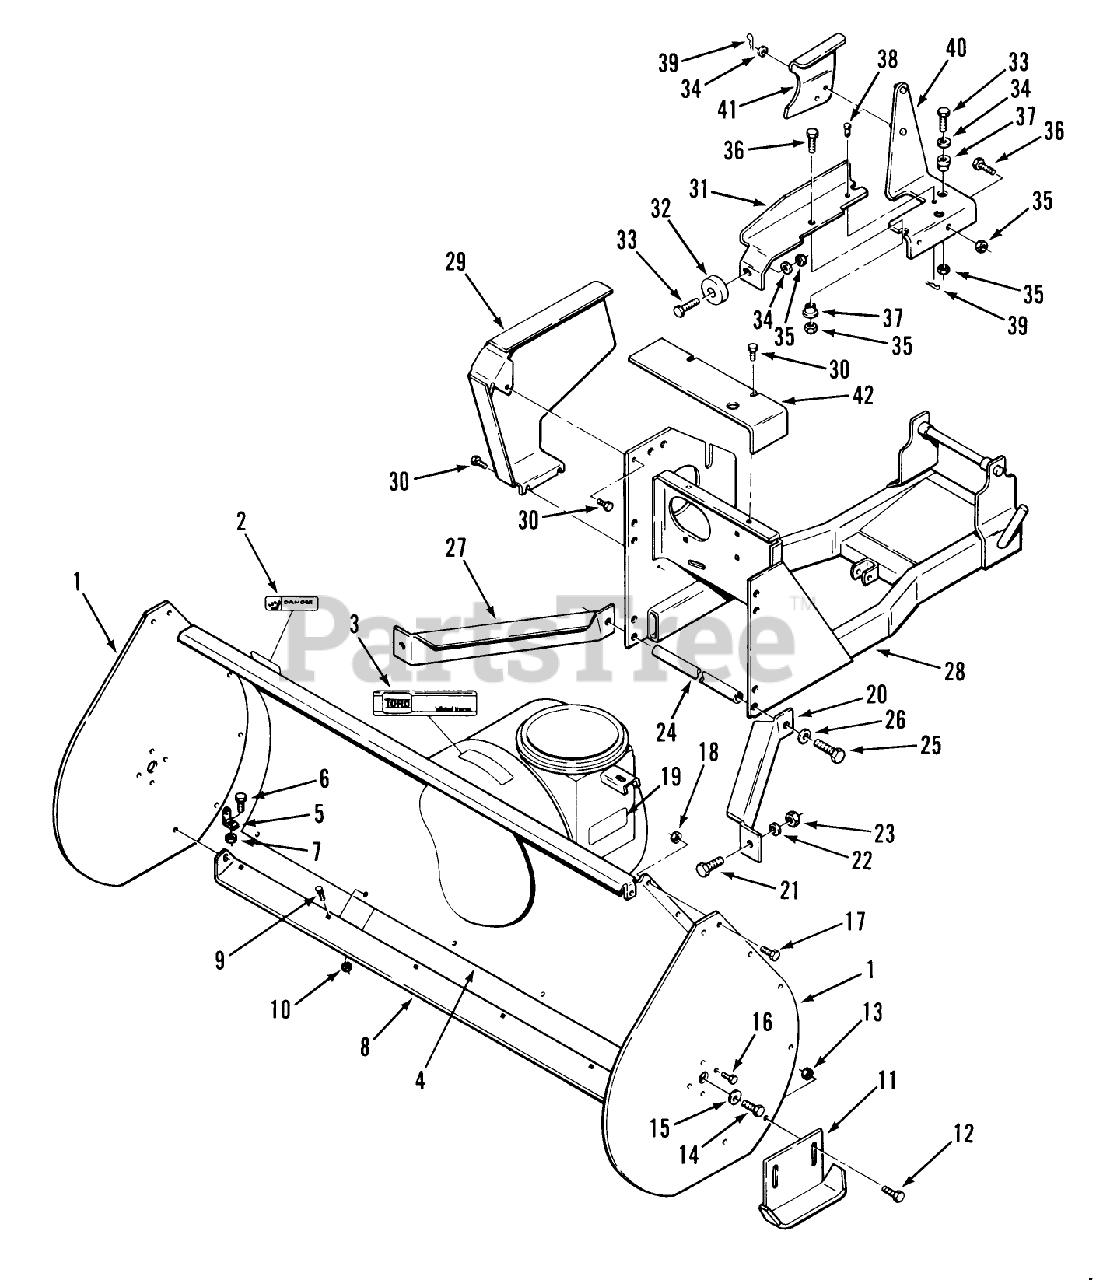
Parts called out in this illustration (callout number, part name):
1	Plate-Side
2	DECAL DANGER
3	Decal
4	Housing-Auger
5	BLADE SUPPORT BRKT R
6	Bolt
7	Nut
8	Blade-Scraper
9	Bolt-Carriage
10	Nut
11	Skid
12	Bolt-Carriage
13	Nut
14	BOLT
15	WASHER
16	Bolt
17	Bolt
18	Nut
19	DECAL-OVERLAY
20	BRACE-L.H. R
21	CARRIAGE BOLT -4
22	WASHER
23	Nut
24	BRACE-CROSS R
25	7/16-14 x 1 1/4 Bolt
26	LOCKWASHER
27	BRACE-R.H. R
28	WLDMT-CARRIER FRA R
29	WLDMT-BELT COVER R
30	Bolt
31	Bracket-Bumper
33	Bolt
34	Washer
35	NUT
36	BOLT
37	SPACER-LIFT LINK
38	CLEVIS PIN
39	Hairpin
40	WLDMT-BRKT GUARD R
41	GUARD-BELT R
42	GUARD R
